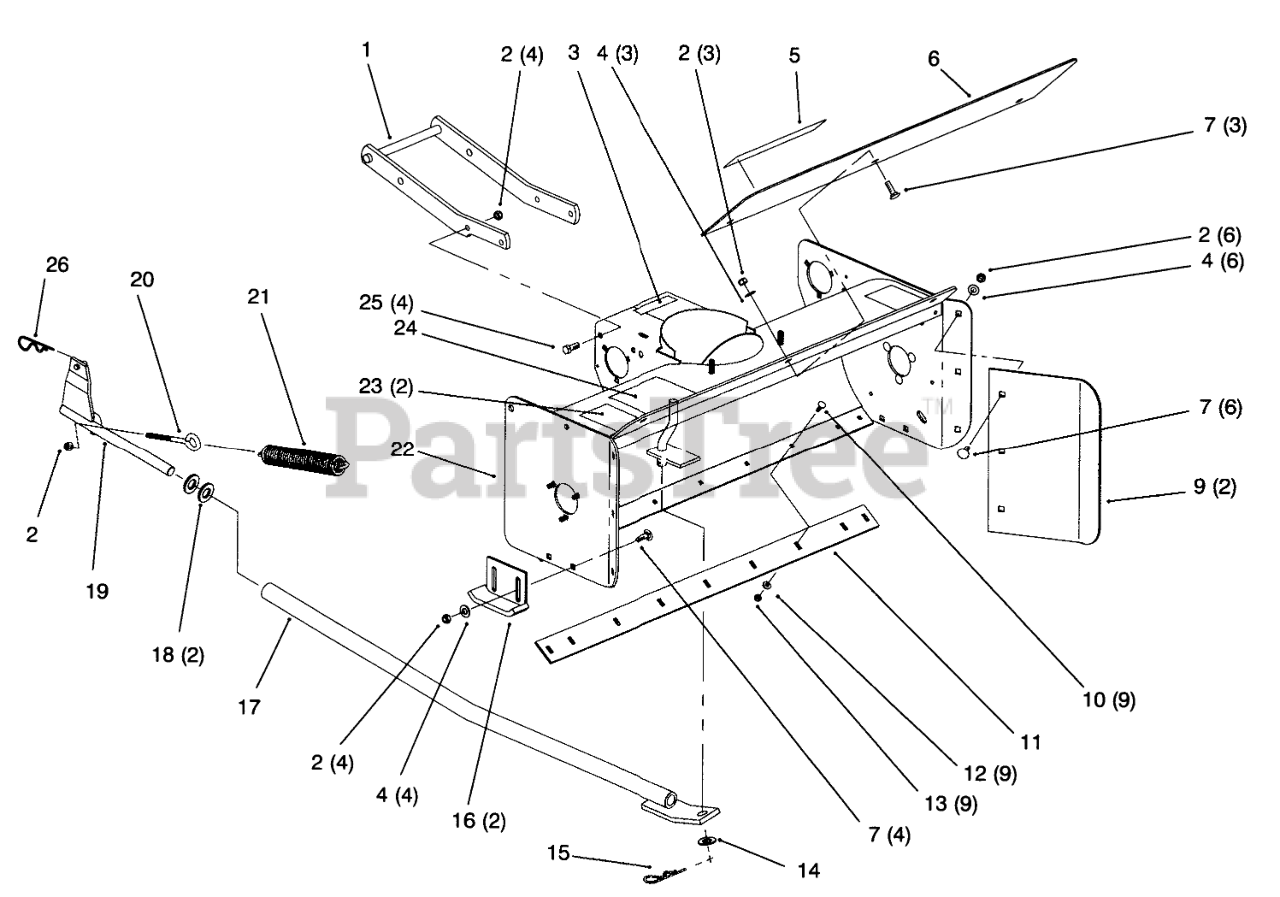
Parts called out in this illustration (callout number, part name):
1	FRAME-MOUNTING
2	NUT-LOCK, NI
4	WASHER-FLAT
5	DECAL-ATTACHMENT
6	PLATE-EXTENSION
7	BOLT-CARR
9	PLATE-EXTENSION, RH
10	SCREW-CARR
11	SCRAPER-REVERSIBLE
12	WASHER-FLAT
13	NUT-LOCK, NI
14	WASHER-FLAT
15	PIN-COTTER, HAIR
17	Lift Tube
18	WASHER-FLAT
19	LIFT ROD ASM
20	EYEBOLT
21	SPRING
22	Auger Housing ASM (Incl. Ref. # 23,24)
23	DECAL-DANGER
24	DECAL-WARNING
25	SCREW-HH
26	PIN-HAIR
